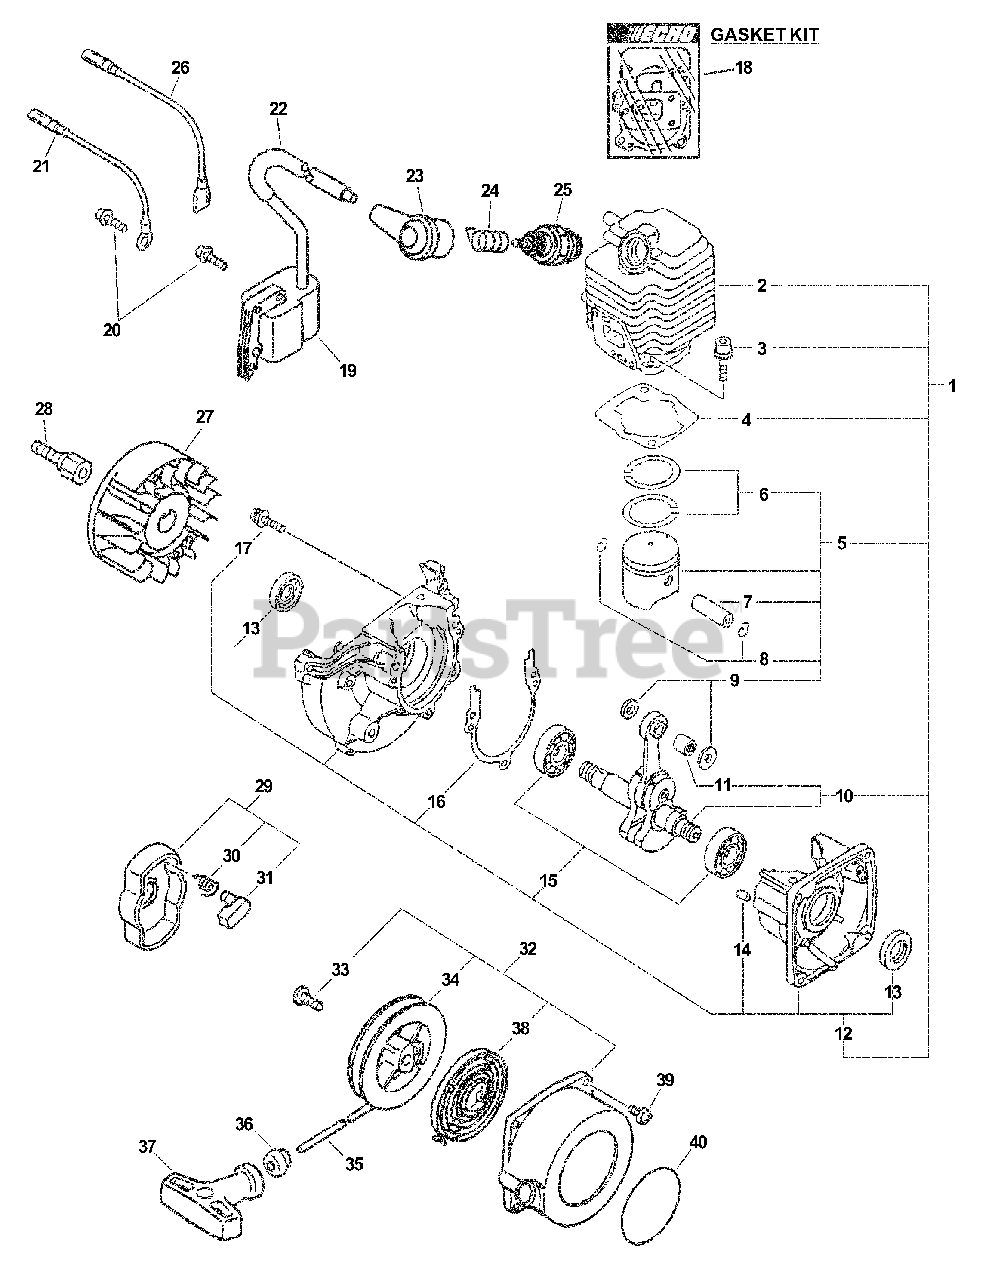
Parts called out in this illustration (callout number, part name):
1	SHORT BLOCK
2	CYLINDER
3	BOLT 5×22
4	GASKET, CYLINDER
5	PISTON KIT
6	RING, PISTON
7	PIN, PISTON 8
8	RING, SNAP
9	WASHER, THRUST
10	CRANKSHAFT ASSY
11	BEARING, NEEDLE
12	CRANKCASE KIT
13	SEAL, OIL 12
14	PIN, LOCATING 4
15	BEARING, BALL - 6201 C3
16	GASKET, CRANKCASE
17	BOLT 5×28
18	GASKET KIT
19	COIL, IGNITION
20	SCREW 4×22
21	LEAD - GROUND
23	CAP, SPARK PLUG
24	TERMINAL, SPARK PLUG
25	SPARK PLUG - BPM-7Y
26	LEAD - IGNITION
27	FLYWHEEL
28	HUB, FAN
29	PAWL ASSY, STARTER
30	SPRING, RETURN
31	PAWL, STARTER - BLACK
32	STARTER ASSY, RECOIL
33	SCREW
34	REEL, ROPE
35	ROPE, STARTER 3.0×1000
36	GUIDE, ROPE
37	GRIP, STARTER
38	SPRING, RECOIL
39	BOLT 4×16
40	LABEL, ECHO
